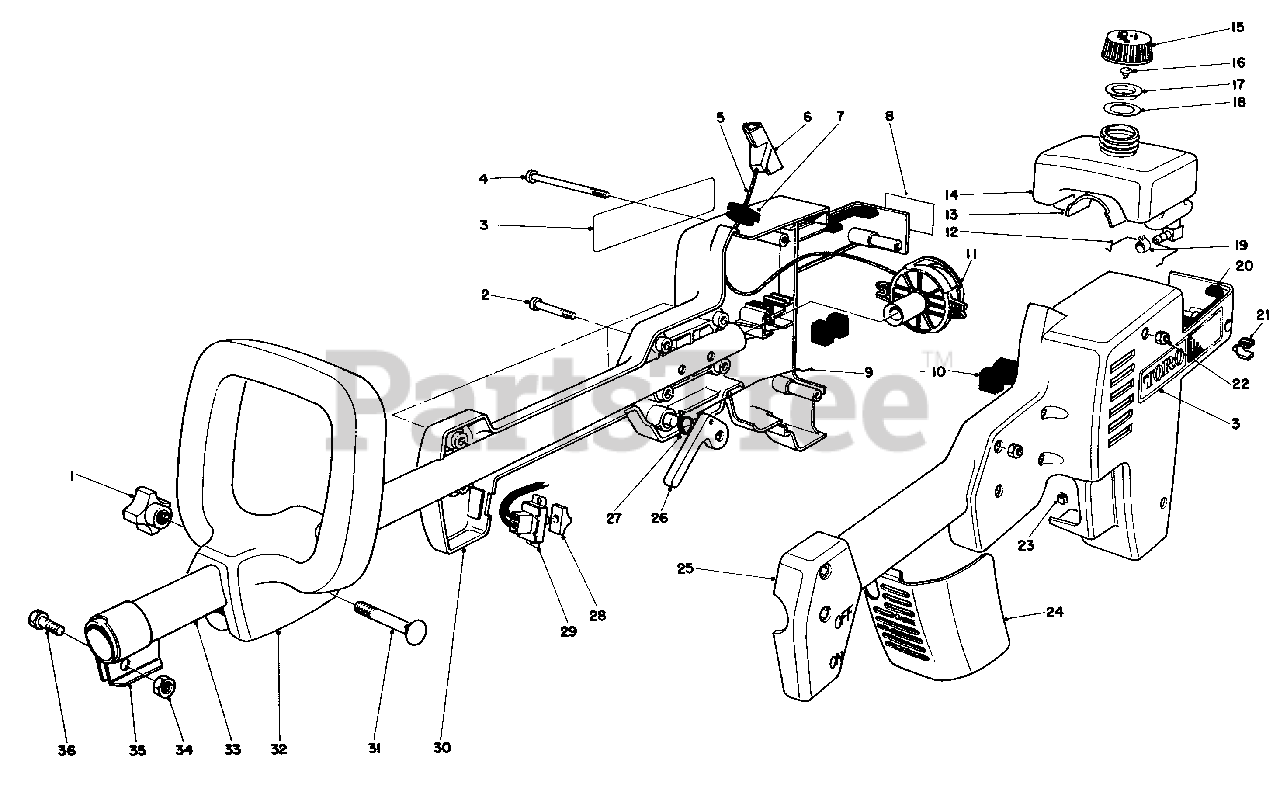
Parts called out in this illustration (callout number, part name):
1	Knob
2	Cross Recess Pan Hd. Machine Screw
3	Decal-Toro TC300
4	Cross Recess Pan Hd. Machine Screw
5	Rope-Starter
6	Handle-Starter
7	Bushing-Rope
8	Decal-Hot Surface
9	Link-Throttle
10	Mount-Isolation
11	Starter Assembly (Incl. Ref. #5-7)
12	Clip-Crankcase Pad
13	Pad-Crankcase
14	Tank-Gas
15	Gas Cap Assembly (Incl. Ref. #16-18)
16	Valve-Umbrella/Combination
17	Insert Gas Cap
18	Gasket-Gas Cap
19	Clamp-Fuel Line
20	Bumper-Gas Tank
21	Grommet
22	Locknut
24	Cover-Air Cleaner
25	Housing-Engine L.H.
26	Lever Throttle
27	Spring-Torsion
28	Cover-Switch
30	Housing Engine R.H. (Incl. Ref. #8)
31	Bolt Carriage
32	Handle-Secondary
33	Tube-Upper Shaft Housing
35	Clamp-Pole
36	Capscrew
